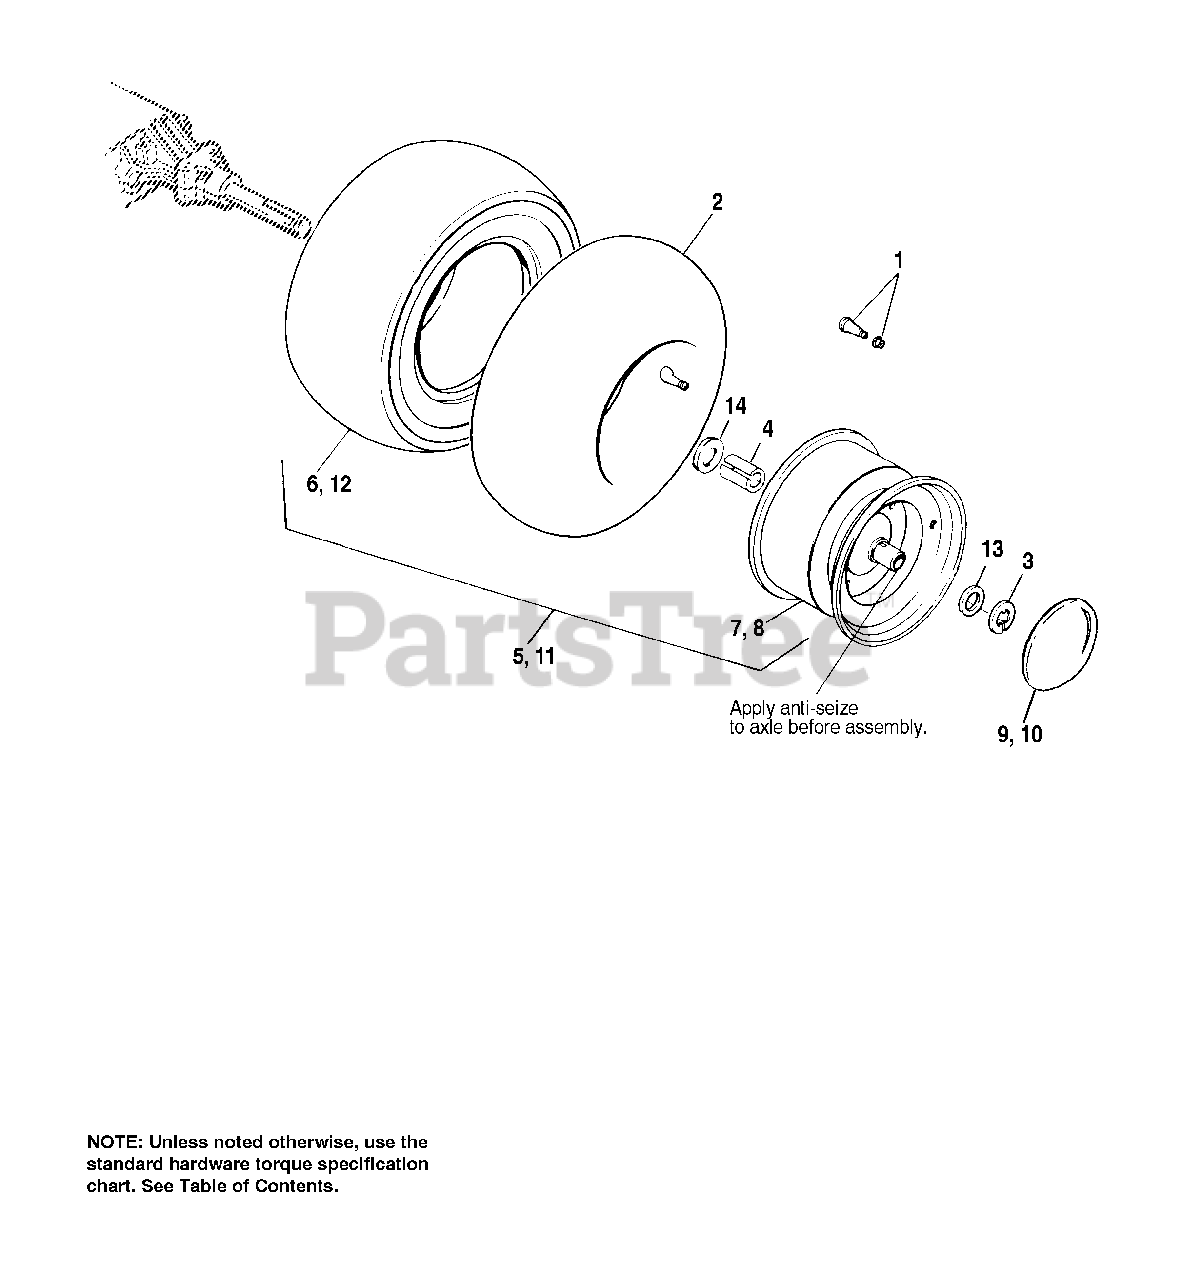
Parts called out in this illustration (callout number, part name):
1	VALVE STEM & CAP
2	TUBE
5	WHEEL & TIRE ASSY., 20 x 8.00-10
6	TIRE, 20 x 8.00-10
7	WHEEL ASSY., Metallic Gray, 20 x 8.00-10
8	WHEEL ASSY., Metallic Gray, 20 x 8.00-8
9	HUB CAP, Smooth, 8"
10	HUB CAP, Scalloped, 8"
11	WHEEL & TIRE ASSY., 20 x 8.00-8
12	TIRE, 20 x 8.00-8
13	WASHER, 3/4
14	WASHER, 3/4
